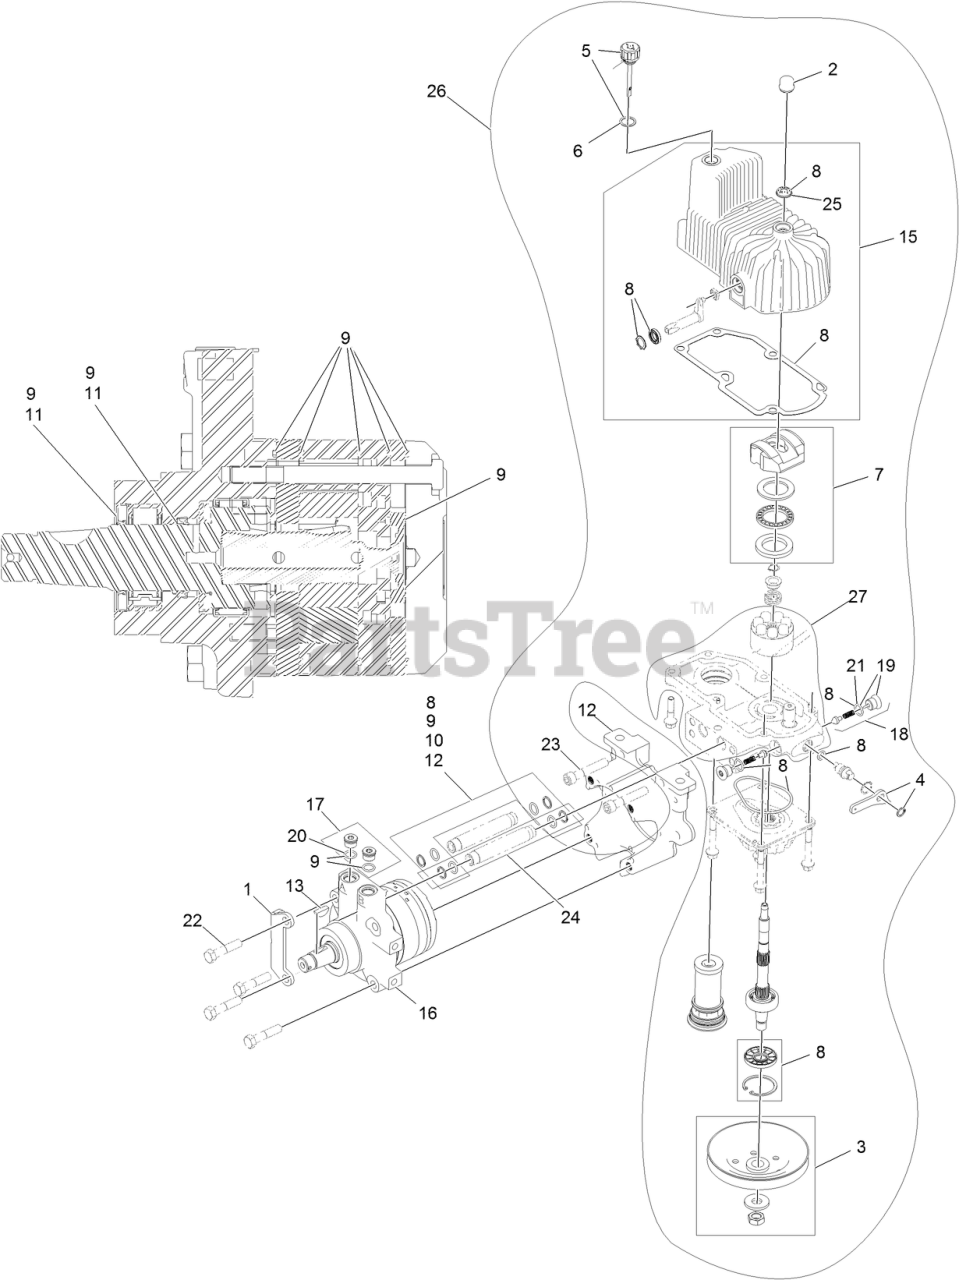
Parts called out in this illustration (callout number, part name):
1	MOUNT-SHOE, HORSE
2	COVER-SHAFT, HYDRO
3	PULLEY KIT
4	HANDLE-BYPASS VALVE, HYDRO
5	DIPSTICK-HYDRO W/GASKET
6	GASKET-DIPSTICK, HYDRO
7	SWASH BLOCK KIT
8	PUMP SEAL KIT
9	MOTOR SEAL KIT
10	TUBE SEAL KIT
11	OUTPUT SHAFT SEAL KIT
12	NOSE CUP-UHT
13	KEY-WOODRUFF
15	HOUSING-HYDRO, RH
16	MOTOR-HYDRAULIC RH 240CC
17	MAGNETIC PLUGS SERVICE KIT
18	CHECK VALVE ASM
19	PLUG-CHECK (W/O-RING)
20	O-RING
21	O-RING-CHECK VALVE
22	SCREW HH
23	SCREW-HSH
24	HYDRAULIC TUBE KIT
25	SEAL-FAN DRIVE
26	KIT, PUMP SECTION 12CC RH NO FAN
27	KIT, ROTATING GRP 12CC RH
